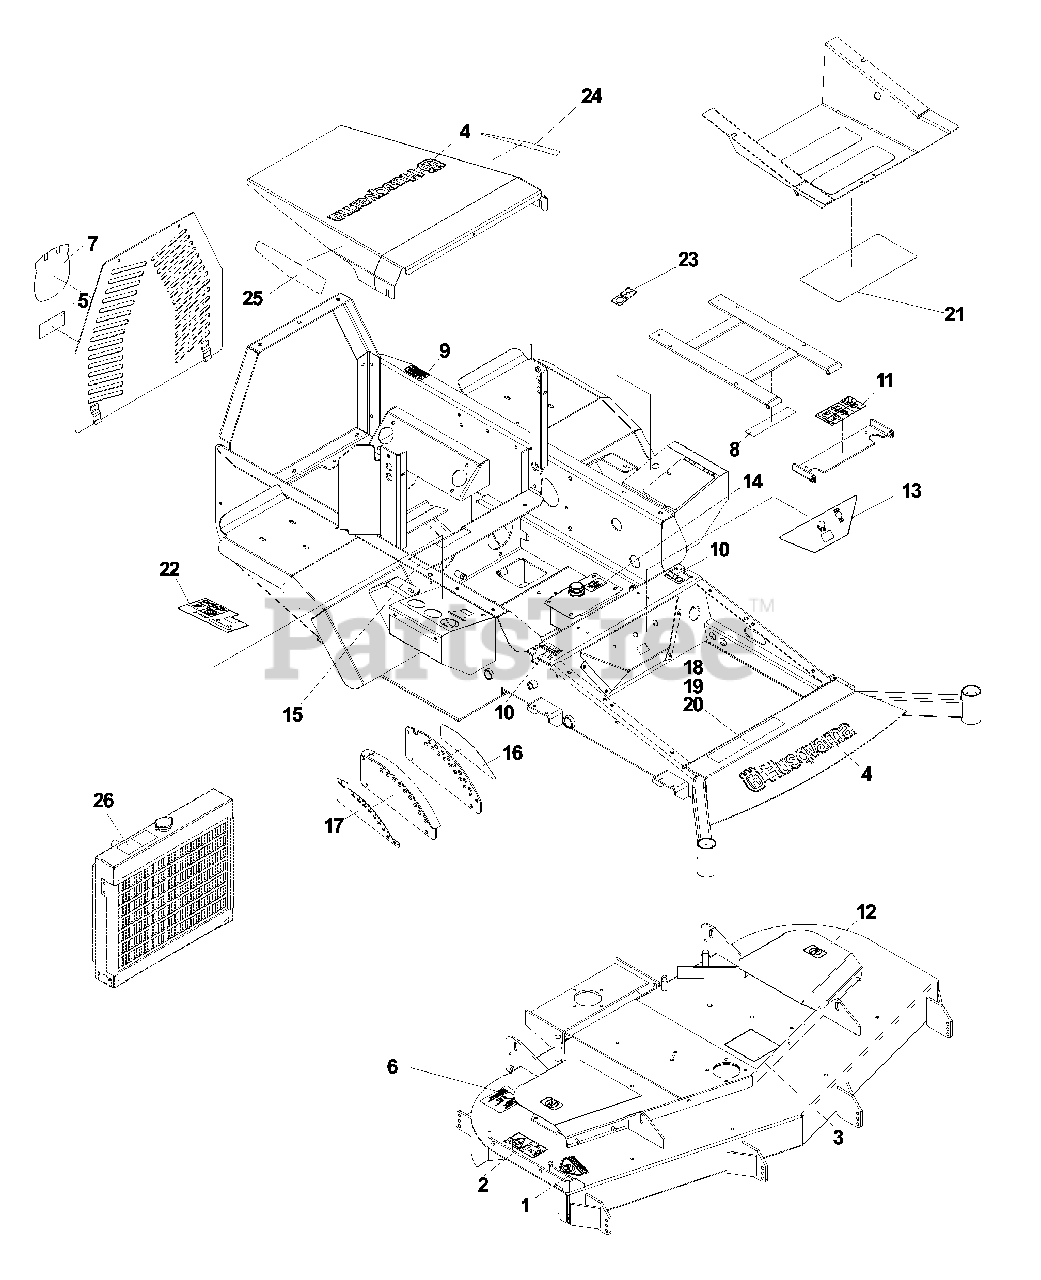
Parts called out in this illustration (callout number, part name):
1	Decal, CPSC
2	Decal, Euro servering
3	Decal, Belt routing
4	Decal, Husqvarna
5	Decal, Euro danger, belt drives
6	Decal, Anti-scalp
7	Decal, crown
8	Decal, Euro battery warning
9	Decal, Prop 65
10	Decal, Motion control
11	Decal, Euro warning
12	Decal, Euro no step
13	Decal, Front Console
14	Decal, Mobil
15	Decal, Fuel valve
16	Decal, Height indication
17	Decal, Height indication
18	Decal, BZ6134D
19	Decal, BZ7234D
20	Decal, BZ6127D
21	Decal, Service
22	Decal, Right Console
23	Decal, 12V DC
24	Decal, 34 Turbo, left
24	Decal, 27 Diesel, left
25	Decal, 34 Turbo, right
25	Decal, 27 Diesel, right
26	Decal, HOT
